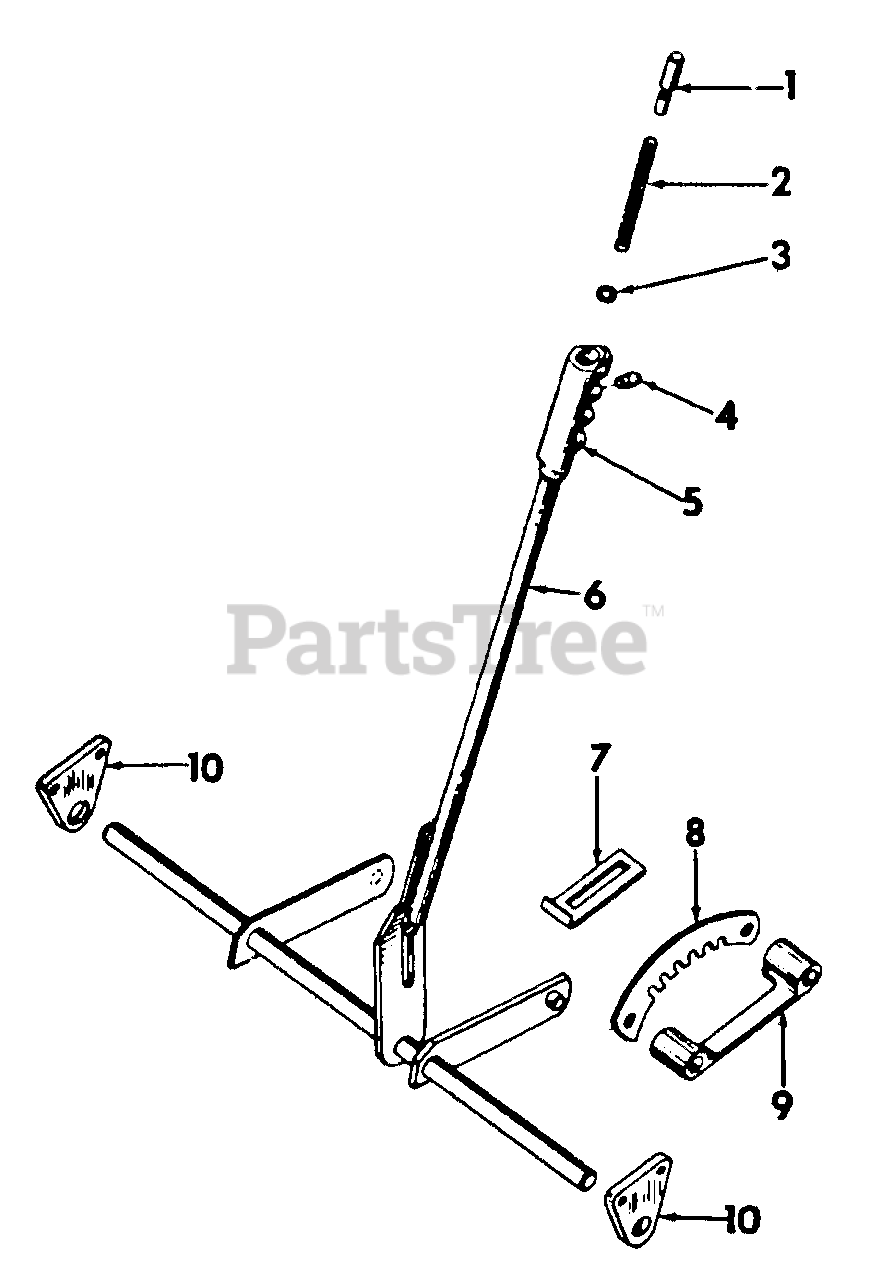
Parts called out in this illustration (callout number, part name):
1	Pin, Release Rod
2	Spring, rod Return
3	Washer, Spring
4	Lock Assy, Release Rod
6	Handle w/Grip, Lift
7	Stop, Lift Arm
8	Ratchet, Lift
9	Spacer Assy, Lift Ratchet
10	Bracket, Lift Handle Shaft
